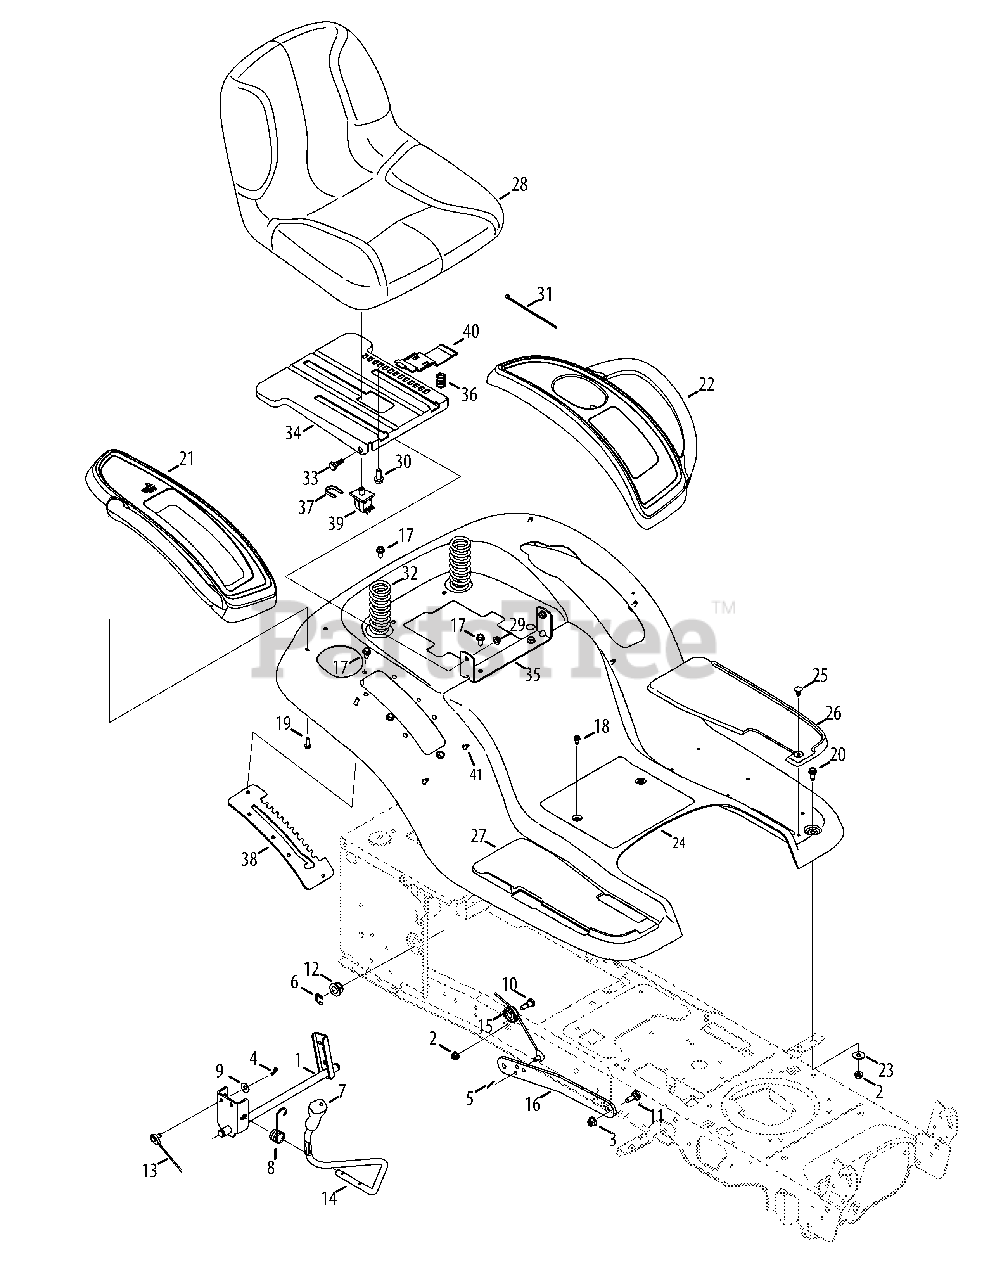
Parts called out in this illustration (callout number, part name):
1	Lift Shaft Assembly
2	Flangelock Nut, 5/16-18
3	Flangelock Nut, 3/8-16
4	Cotter Pin, .072 DIA. x 1.13 LG
5	Bow-Tie Cotter Pin
6	E-Ring, .625 DIA. SHAFT
7	Handle Grip
8	Torsion Spring
9	Spring Washer, .401 x .870 x .063
10	Shoulder Screw, .437 x .470 x 5/16-18
11	Shoulder Bolt, .500 x .270 x 3/8-16
12	Hex Flange Bearing
13	Lift Cable, 16.64 LG
14	Lift Handle
15	Pulley Roller Cable
17	Taptite Screw, Lock Washer, 5/16-18
18	Taptite Screw, Lock Washer, 1/4-20
19	Hi-Lo Screw, Lock Washer, 1/4-15
20	Taptite Screw, 5/16-18 x .750
21	Fender Cover RH
22	LH Fender Cover
23	Flat Washer, .344 x 1.00 x .063 HDN
25	Ratchet Clip
26	LH Foot Pad
27	RH Foot Pad
28	Seat
29	Flangelock Nut, 5/16-18
30	Hex Head Flange Bolt, 3/8-16 x .875
31	Cable Tie, 3/16 x .05 x 7.4
32	Compression Spring, 1.50 x 3.90 x .200
33	Shoulder Screw, .437 x .268 x 5/16-18
34	Seat Mounting Bracket
35	Seat Pivot Bracket
36	Comp. Spring, .68 x 1.065 x .055
37	Switch Retainer Clip
39	Seat Switch
40	Seat Adjustment Lever
41	Screw, 1/4-15 x 0.50
